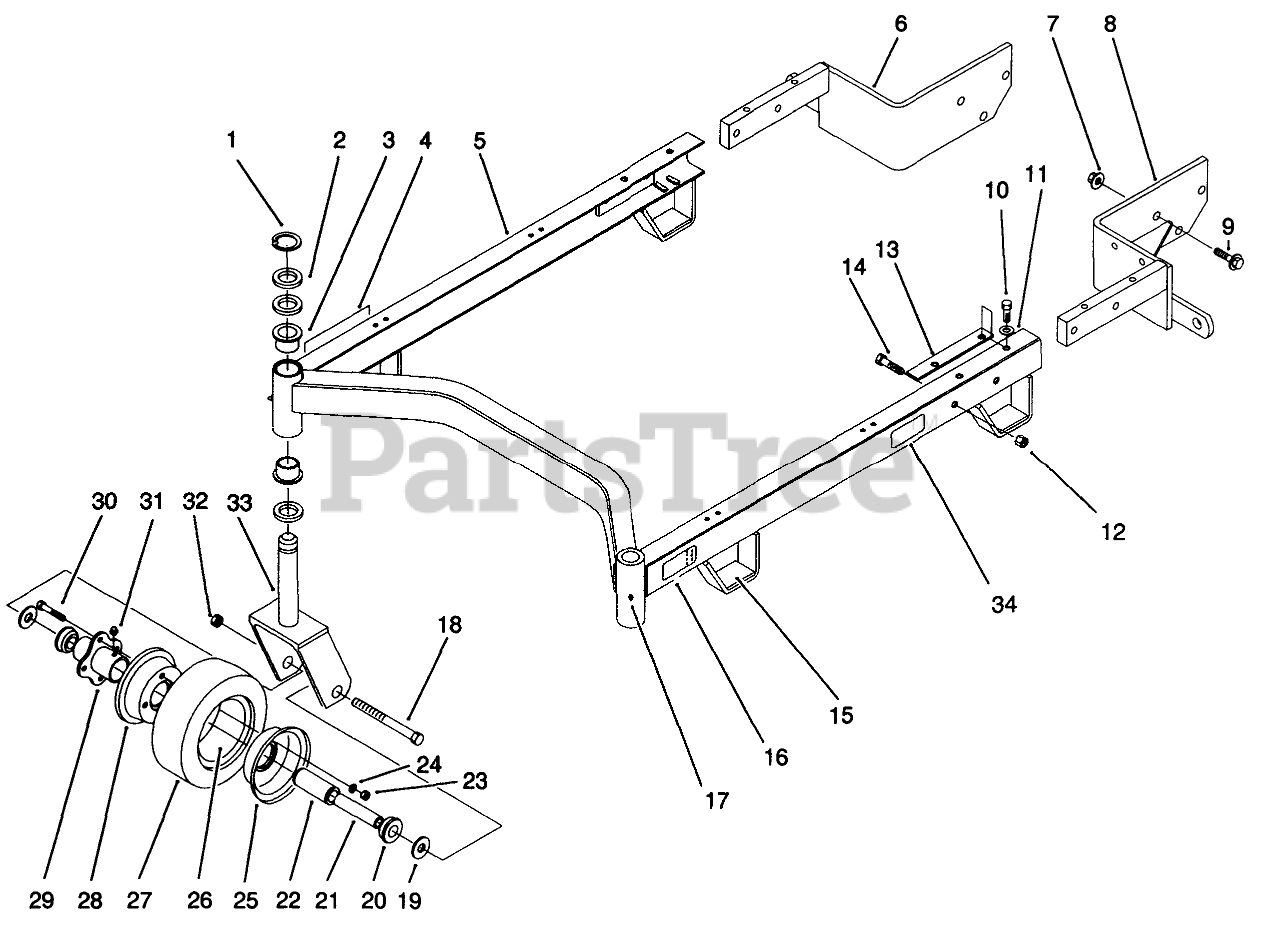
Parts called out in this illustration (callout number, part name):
1	RING-RETAINING
2	WASHER-THRUST
3	Bushing
4	DECAL-HOC, LH
5	Suspension Frame W.A.
6	Angle Bracket Ass-y R.H.
7	NUT-HF
8	Angle Bracket Ass-y L.H.
9	SCREW-HHF
10	SCREW W/PATCH
11	WASHER-FLAT
12	NUT-LOCK, CONE
13	SHIM-CARRIER
14	SCREW-HH
15	CUSHION-RUBBER
16	DECAL-HOC, RH
17	FITTING-GREASE
18	SCREW-HH
19	WASHER-FLAT
20	BEARING-OUTSIDE
21	SPANNER-TIRE
22	BEARING-ROLLER
23	NUT-HEX
24	WASHER-LOCK
25	MALE WHEEL HALF
26	TUBE-INNER (W/VALVE)
28	FEMALE WHEEL HALF
29	HUB-CENTER
30	WHEEL BOLT
31	FITTING-GREASE
32	NUT-HEX
33	Castor Fork
34	DECAL - HOC
